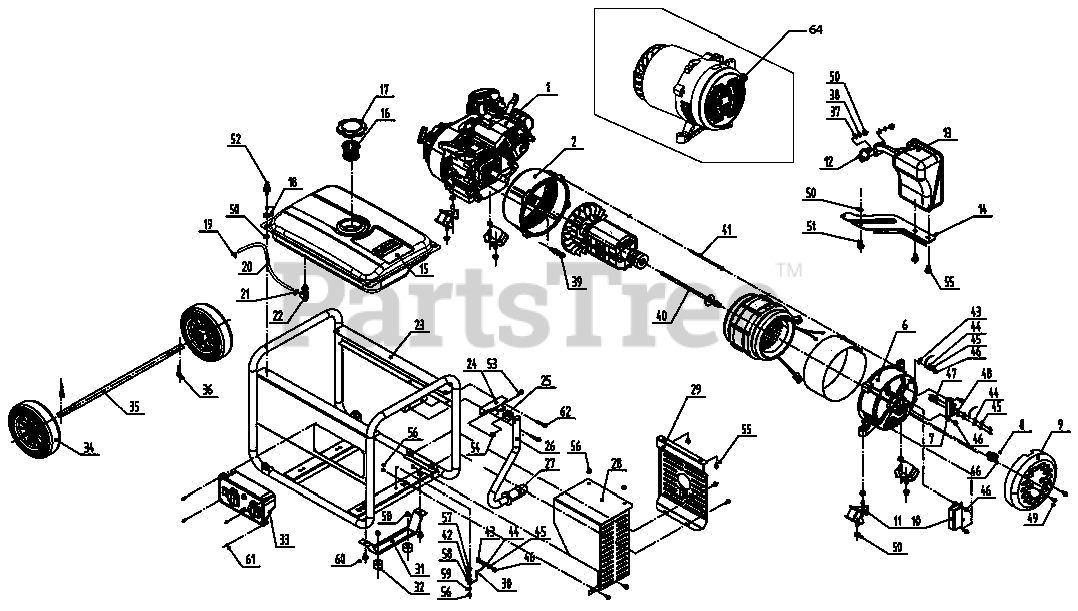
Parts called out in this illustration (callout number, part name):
1	208cc Engine
2	Adaptor Casting, Eng/ALT 3250W
6	Rear Bearing Carrier 190
7	Wire Fasten Connection
8	Assembly Brush 3.25kW Portable
9	Cover, Alternator 3.25kW
11	Vib Mount 35 X 15 X M8-1.25
12	Muffler Gasket
14	Muffler Bracket
15	Fuel Tank
16	Fuel Tank Filter
17	Fuel Tank Cap
18	Rubber Mount 8 ID X 5 HGT
20	Fuel Hose, 4.5 ID, 8.5 OD, 160 LG
22	Valve Fuel Shutoff 4Gal Tank
23	Assy Frame GP3250 1-Piece
24	Bracket, Handle 3.25kW Portable
25	Spacer Handle Plastic 3.25kW
26	Handle 3250W GP
27	Handle Cover
28	Heat Shld Exhst Frnt 163/208CC
29	Heat Shield, Exhaust Side
30	Grounding Wire
31	Bracket Foot 3.25kW Portble
32	Vib Mnt 38.1 X 25.4 X M8-1.25
33	Control Pannel
34	Wheel , 8" Never-Flat 3.25kW
36	Cotter Hairpin 2.56 X .80
37	Flat Washer
38	Spring Washer
39	Flange Bolt M8x25
40	Rotor Bolt 5/16X210
41	Stator Bolt M6x130
42	Spring Washer
43	External Tooth Lock Washer
44	Flat Washer
45	Spring Washer
46	Flange Bolt M5x16
47	Full-Thread Bolt M5x20
48	Nut M5
49	Flange Bolt M5x12
50	Flange Nut M8
51	Flange Bolt M8x35
52	Flange Bolt M8x25
53	Flange Bolt M6x40
54	Blocking Nut M6
55	Flange Bolt M6x12
56	Flange Nut M6
57	Flange Bolt M6x14
58	Flat Washer
59	Washer Lock Ext 1/4 STL
60	Flange Bolt M8x16
61	Screw PPPH #8-16 X .66" BZC
62	Flange Bolt M8x40
63	Gauge, Fuel
64	Alternator Assy., Complete
